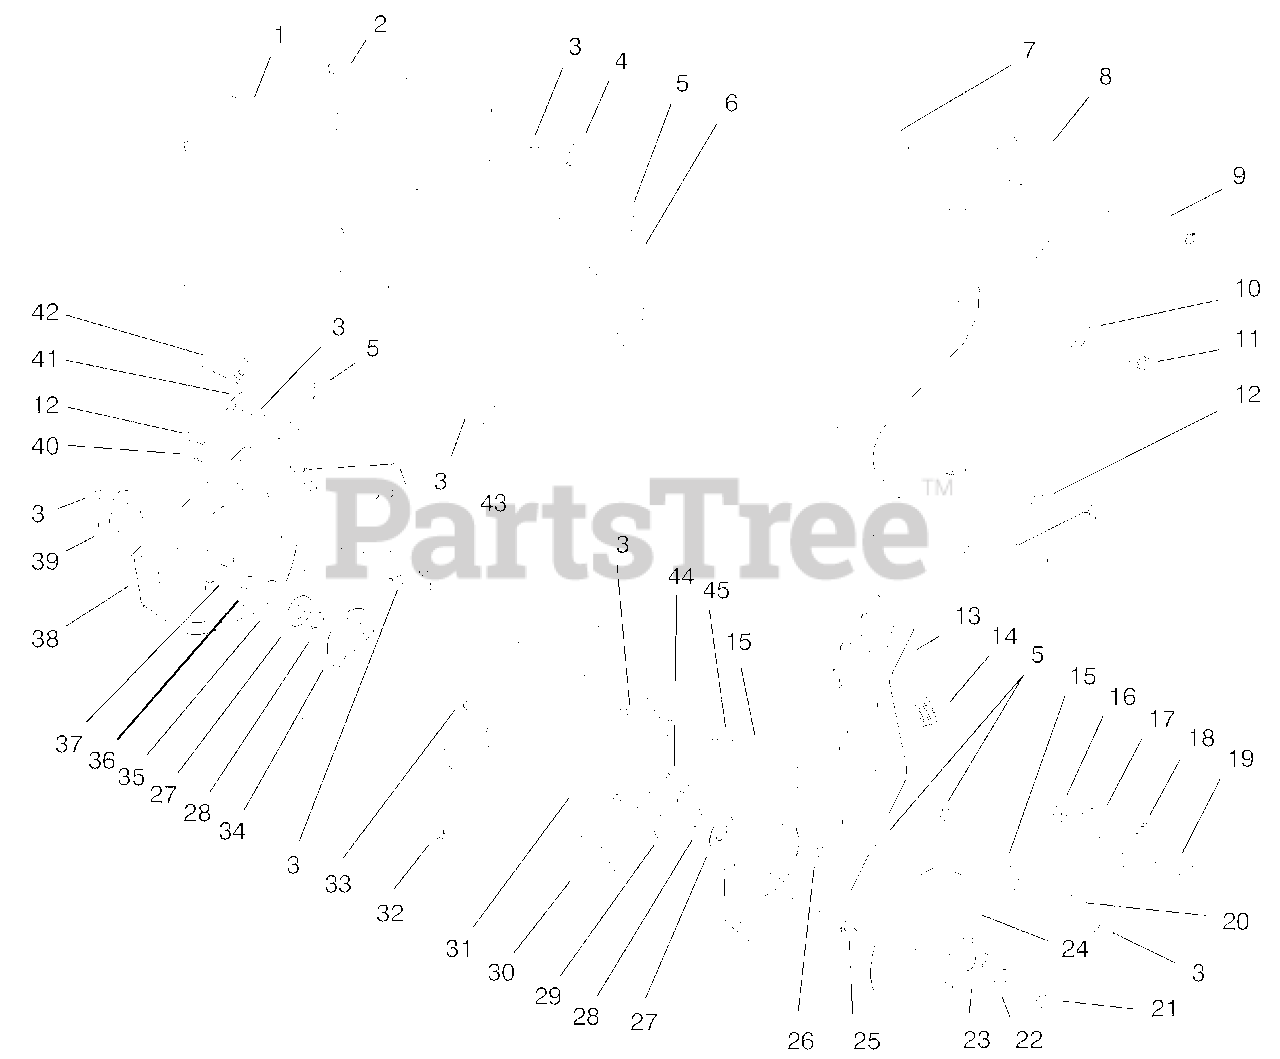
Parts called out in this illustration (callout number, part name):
2	Speed Nut
3	Nut-Lock Ni
4	Hsg Brkt
5	Screw-HH
6	Washer-Flat
7	Tubular Spacer
8	Drive Cover
9	Thread Forming Screw
10	Edge Guard
11	Spec Screw
12	Screw-Machine
13	Left Sideplate
14	Brake Spring
15	Washer-Flat
16	Nut-Lock Ni
17	Brake Arm Idler
18	Idler Pulley
19	Screw-HH
21	Screw-HH
22	Washer-Belleville
23	Hub-Mtg, Pulley
24	Rotor Pulley
27	Bearing-Ball
28	Thrust Washer
29	Bearing Flange
31	Lower Housing
32	Flange Locknut
33	Screw-CARR
34	Brg Flange Wa
35	Rubber Washer
36	Washer-Flat
37	Flange Bolt
38	RH Sideplate
39	Brg Retainer
40	Screw-HH
41	Sideplate Brkt Supt
42	Bracket Cover
43	Washer-Flat
44	Nut-Lock Ni
45	Screw-HH
